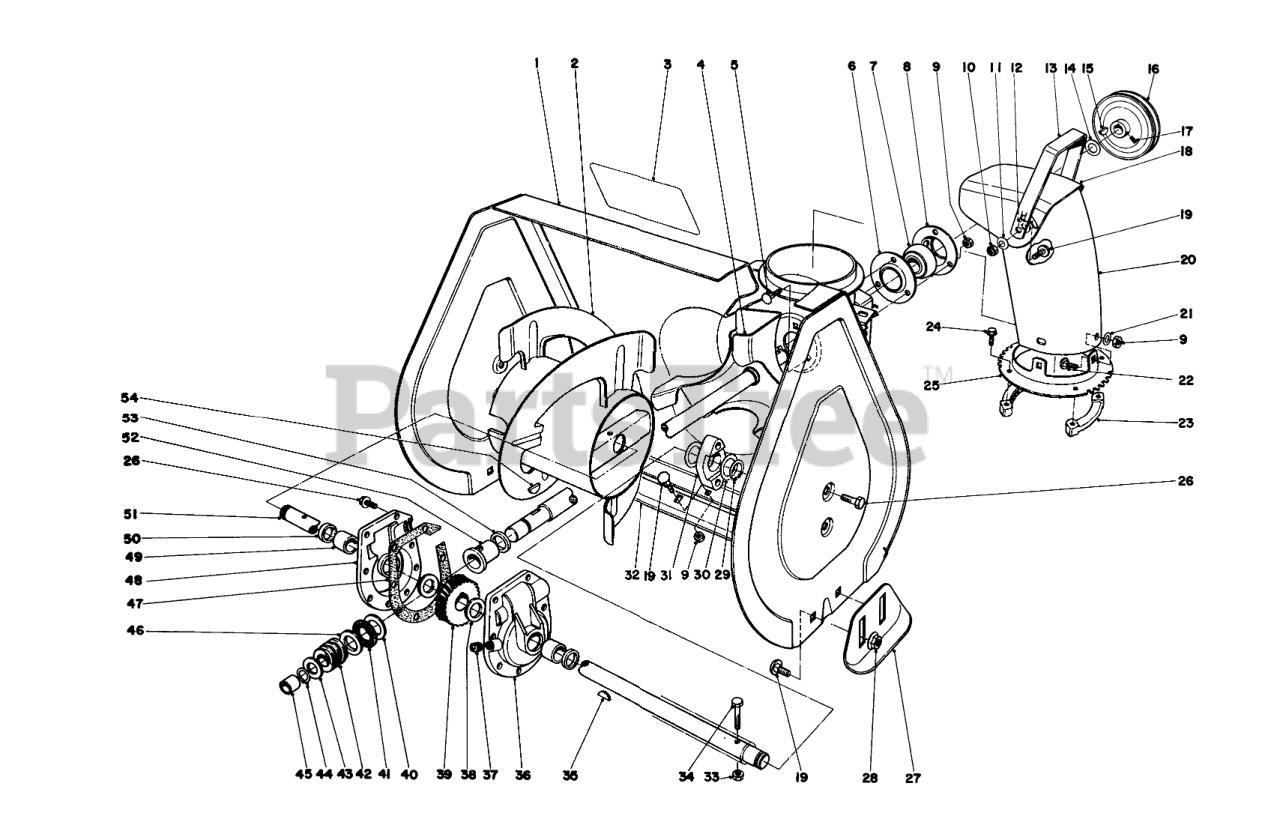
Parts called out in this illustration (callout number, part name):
1	Auger Housing
2	Auger L.H.
3	Decal-Warning
4	Shaft & Impeiler
5	BOLT-CARR
6	FLANGE-CUP, BEARING
7	Ball Bearing
8	FLANGE-CUP, BEARING
9	NUT-LOCK, NI
10	NUT-LOCK, CONE
11	WASHER-BELLEVILLE
12	WASHER-RUBBER
13	Handle Deflector
14	WASHER
15	KEY-WOODRUFF
16	PULLEY
17	SCREW-SET, SQH
18	Deflector
19	BOLT-CARR
20	Chute-Discharge
21	WASHER-PLAIN
22	SCREW-CARR
23	RING-CHUTE, RETAINER
24	SCREW-SPECIAL
25	Chute Ring
26	SCREW-HWHTF
27	Skid
28	NUT-HF
29	RING-RETAINING
30	WASHER
31	BEARING-AUGER
32	Blade-Scraper
33	NUT-LOCK, CONE
34	SCREW-HH
35	KEY-WOODRUFF
36	Gear Case R.H. (Incl. Ref. #49 & 50)
37	PLUG-PIPE, SQH
38	WASHER-THRUST
39	Gear
40	WASHER-THRUST
41	BEARING-THRUST
43	WASHER-THRUST
44	Ring-Snap
45	BUSHING
46	WASHER-THRUST
47	Gasket
48	Gear Case L.H. (Incl. Ref. #49 & 50)
49	BUSHING
50	SEAL-OIL
51	AUGER SHAFT
52	BUSHING-INPUT
53	RING-QUAD
54	KEY-WOODRUFF
